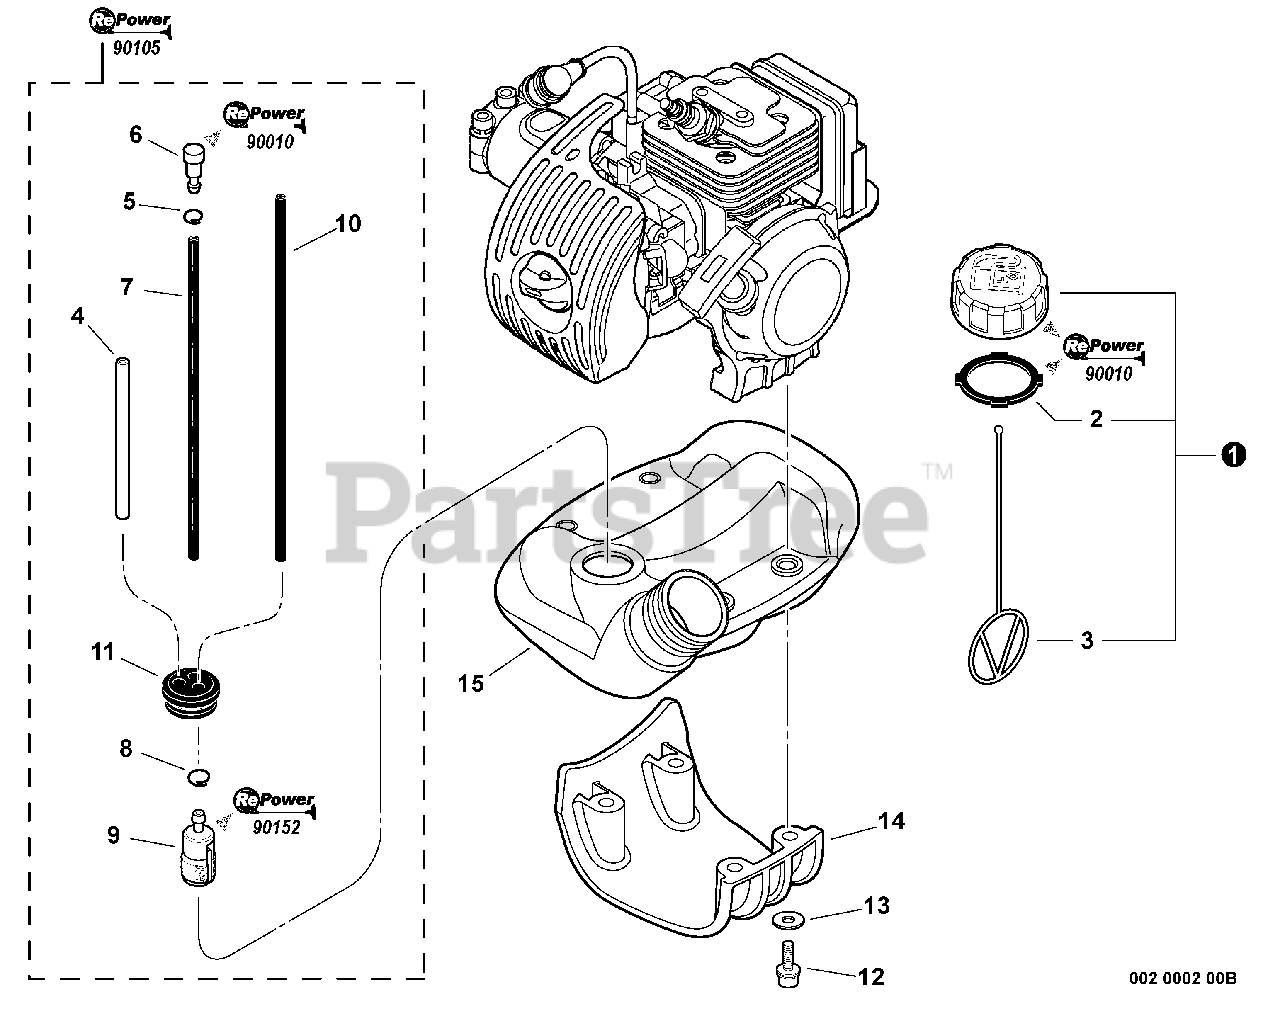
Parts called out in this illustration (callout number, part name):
1	CAP ASSY - ORANGE
2	GASKET, CAP
3	CONNECTOR, CAP
4	PIPE - 3X6X75 -- CLEAR
5	CLIP - 6.5
6	VENT, FUEL TANK
7	PIPE - 3X6X35 -- BLACK
8	CLIP - 6
9	FILTER, FUEL
10	PIPE - 3X5X195 -- BLACK
11	GROMMET
12	SCREW - 5X25
13	WASHER - 5
14	GUARD, FUEL TANK
15	FUEL TANK ASSY
16	RePower FUEL SYSTEM KIT
17	RePower TUNE-UP KIT
18	Repower CAP AND VENT KIT
